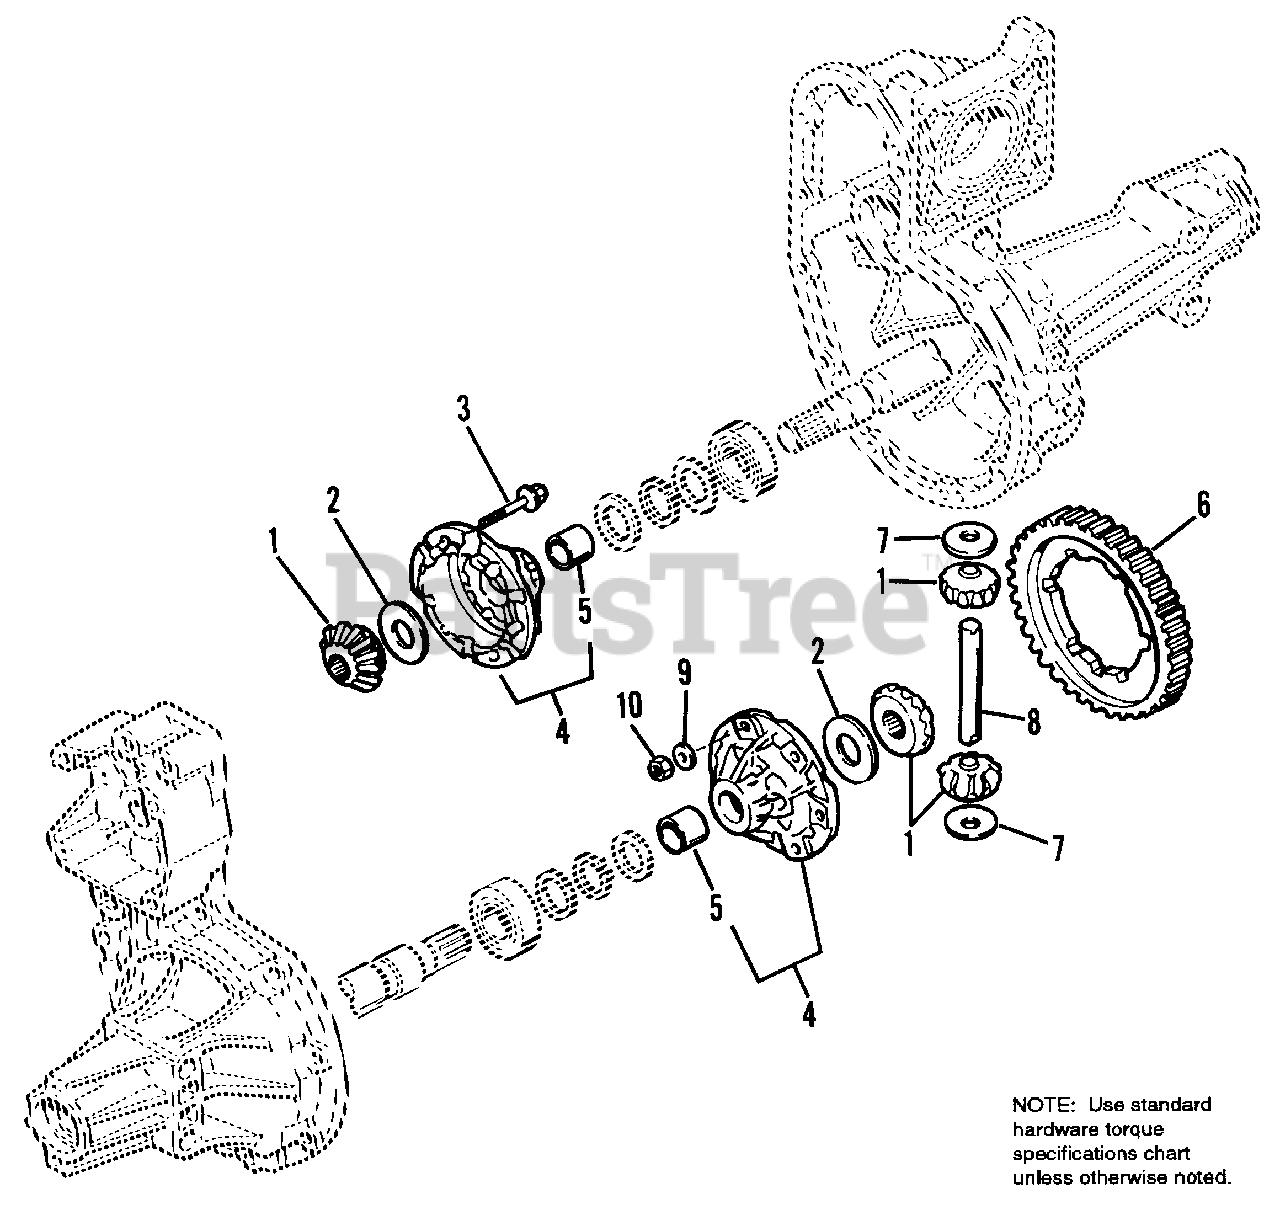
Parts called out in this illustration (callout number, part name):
1	GEAR SET, Differential
4	CASE ASSY., Differential (Includes Ref. No. 5)
6	GEAR SET, Final, 59 Tooth
7	WASHER, Differential Pinion
8	SHAFT, Differential Pinion
